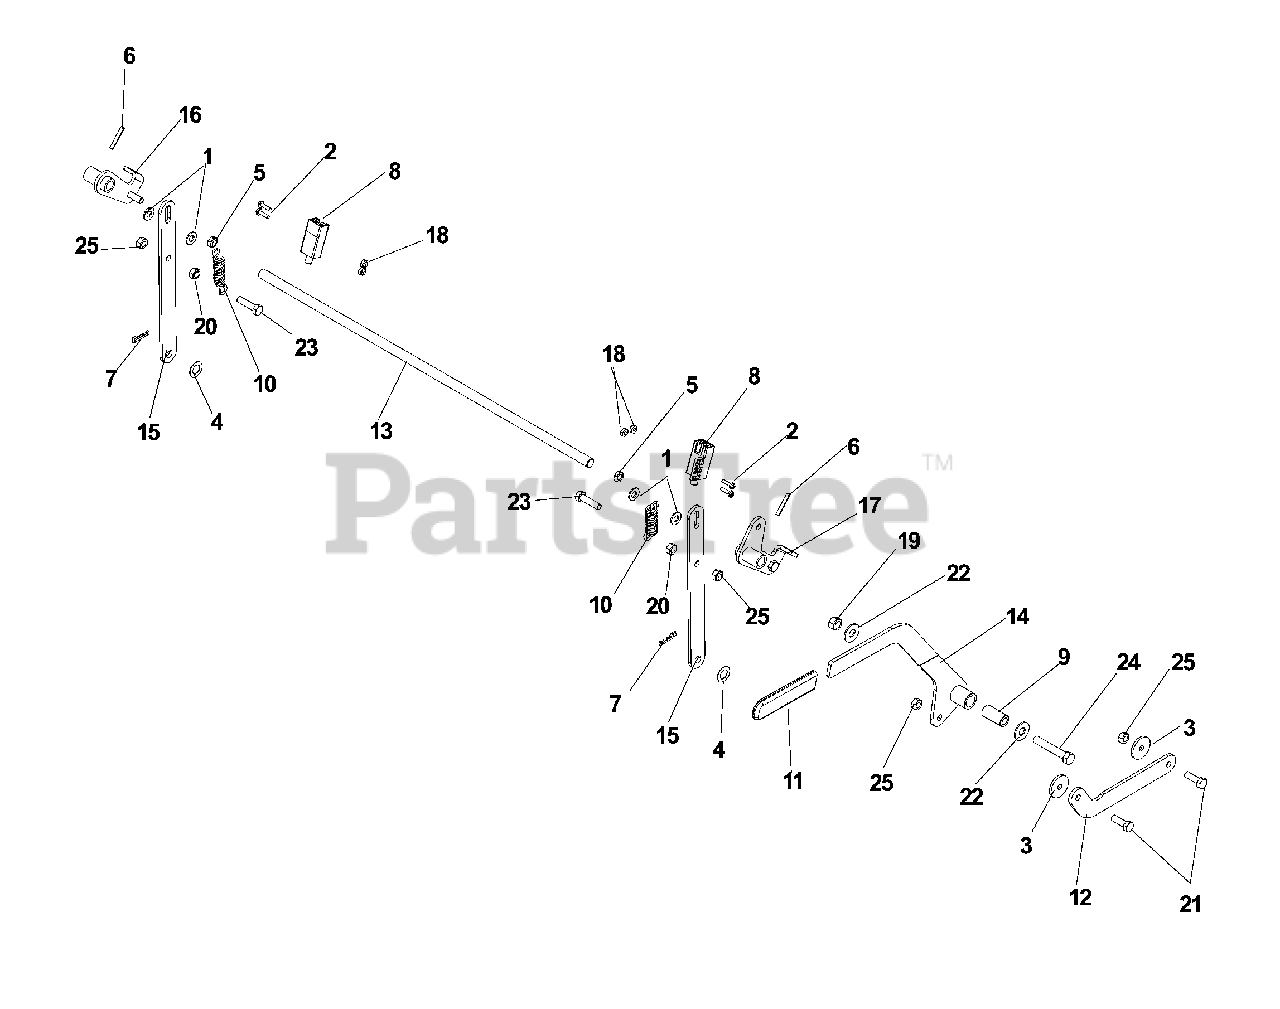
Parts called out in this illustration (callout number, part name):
1	5/16STD FL WASH TYPA
2	SCREW #10-24 X 5/8
3	5/16ID X 1/8THK WASHER
4	WASHER .515 X .874 X .031
5	5/16-18 THIN PROF NY
6	ROLL PIN 3/16 X 1-1/4
7	COTTER HP .08 DIA X 1.19
9	BUSHING
11	GRIP BRAKE HANDLE
12	BRAKE LINK
13	BRAKE ROD
14	BRAKE HANDLE WLDT.
15	BRAKE SLIDE ARM
16	BRAKE PIVOT RH
17	BRAKE PIVOT LH
18	NUT 10-24 NYLOC
19	NUT 3/8-16 NYLOC
20	NUT 5/16C HEX
21	HCS 5/16C X 1
22	WASHER 3/8 FLAT
23	HCS 5/16C X 1 1/4
24	HCS 3/8C X 2 1/4
25	NUT 5/16 NYLOC
